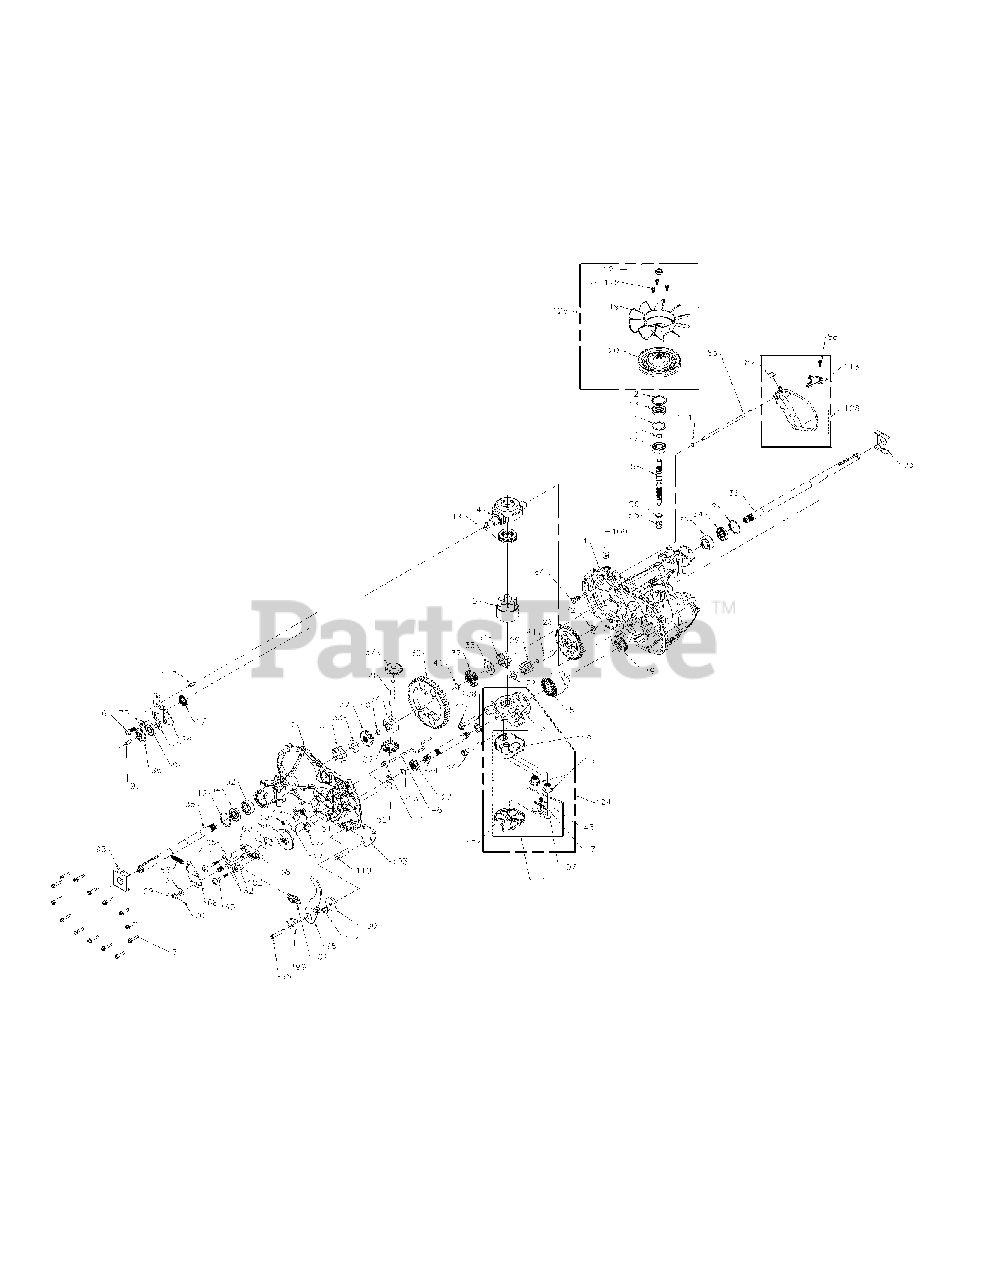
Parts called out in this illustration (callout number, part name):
1	Main Housing, Assembly
1	Main Housing
1	Bushing .865 X .985 X .790
1	Pin, Standard Headless
2	Side Housing, Assembly
2	Side Housing
2	Bushing .865 X .985 X .790
2	Bushing .624 X .719 X .562
3	Center Section, Assembly
3	Center Section
3	Bushing .707 X .788 X .591
4	Trunnion, Swashplate
5	Block, Assembly
5	Block, Cylinder
5	Piston
5	Spring, Compression
5	Washer, Thrust
7	Screw, Hex Flange 1/4-20 X 1.25
9	Shaft, Input
10	Ring, Retaining
12	Ring, Retaining
13	Seal, Lip 17 X 40 X 7
14	Bearing Ball 17mm ID X 40mm OD X 12mm
16	Bolt, Hex Flange Head 5/16-24 X .94 (Patch)
17	Seal, Lip 18 X 32 X 7
18	Arm, Control
19	Bearing, Thrust 30 X 52 X 13
23	Check Plug Assembly, .027 Washer
24	Shaft, Motor
27	Gear, 13T Pinnion
28	Gear, 10T/48T
29	Gear 10T Jackshaft
30	Gear, 60T Bull
31	Bushing, Sleeve (Inboard)
32	Bushing, Sleeve .75 X 1.575 X .625
33	Washer, 3/4 ID X 1-1/2 OD X .13 THK
34	Seal, Lip .75 X 1.577 X .250
35	Shaft, Axel .75 X 12.14 (Keyed, R.H.)
36	Shaft, Axel .75 X 17.74 (Keyed, L.H.)
37	Kit, Miter Gear
37	Gear, Miter 12T (Splined)
37	Gear, Miter 12T (.50 ID)
37	Bulletin, Miter Gear
39	Shaft, Diff
40	Ring, Spiral Retaining
41	Pin, Jackshaft
42	Magnet, Ring
43	Spring, Bypass
44	Bolt, Hex Flange 3/8-24 X 2.5
45	Bottom, Filter
46	Base, Filter with Poppet
47	Actuator, Bypass
48	Rod, Actuator Bypass
49	Arm, Bypass
50	Ring, Retaining .250 External
51	Seal, Lip .250 X .750 X .250 TC
52	Washer, Flat 5/8 ID X 1.0 OD X .05
53	Ring, Retaining
54	Bushing, Center Block
55	Spring, Block
56	Washer, Thrust
58	Kit, Brake Yoke
58	Yoke, Brake
58	Bolt, SQ.HD. 5/16-24- Ribbed
59	Rotor, Brake
60	Puck, Brake
61	Plate, Puck
62	Pin, Brake Actuating
63	Screw, Special Flange 1/4-20 X 2 W/ Patch
66	Spring, Brake Arm Bias
68	Arm, Brake
69	Nut, Castle 5/16-24
70	Pin, Cotter 3/32 X 3/4
71	Spring, Compression Brake Anti-Drag
72	Washer, HT .5 ID X 1 OD X .032
73	Washer, Flat 11/32 ID X 7/8 OD
74	Seal, Lip .625 X 1.0 X .25
84	Fitting, 5/16 SAE 5/32 Tube
85	Hose, Expansion Tank
87	Cap, Expansion
88	Bolt, Self Tapping 10-32 X1/2
93	Spring Clip, Housing Thrust
94	Bearing, Ball .62 ID X 1.38 X .44
95	Screw, Socket Head Cap 5/16-24 X 1-1/2
96	Spacer, Locating
97	Screw, Countersunk 5/16-18 X 1
98	Arm, Return
99	Puck, Adjusting
100	Washer, .32 OD X 1.60 ID X .24
101	Spring, Extension Double Loop
102	Spacer, .260 ID X .560 OD X .870
103	Bracket, Torque
107	Deflector
108	Washer, Motor Shaft .71 ID X 1.15 OD X .030 THK
109	Plug, 9/16-18 (Metal)
110	Screw, Torx Head 5/16-18 T.F.
111	O-Ring .103 ID X .299 OD
113	Bracket, Support Expansion Tank
114	Spring Guide
117	Pin, Spring
119	Fan, 7 IN 10 Blade
120	Pulley, 4.79 Inch
121	Nut, Hex Lock 1/2-20 (Nylon Insert)
122	Screw, Tapping, Hex Washer Head, 12-24 X .50
124	Center Section, Filter, Bypass Assembly
124	Center Section
124	Base, Filter with Poppet
124	Check Plug Assembly, .027 Washer
124	Spring, Bypass
124	Actuator, Bypass
124	Deflector
124	Bottom, Filter
124	Bushing, .707 X .788 X .591
125	Filter Assembly
125	Bottom, Filter
125	Base, Filter with Poppet
125	Spring, Bypass
125	Actuator, Bypass
125	Deflector
126	Kit, Fan/Pulley
126	Fan, 7 IN 10 Blade
126	Pulley, 4.79 Inch
126	Nut, Hex Lock 1/2-20 (Nylon Insert)
126	Screw, Tapping, Hex Washer Head, 12-24 X .50
128	Kit, Expansion Tank
128	Tank, Expansion
128	Cap, Expansion
128	Bolt, Self Tapping 10-32 X1/2
128	Bracket, Support Expansion Tank
